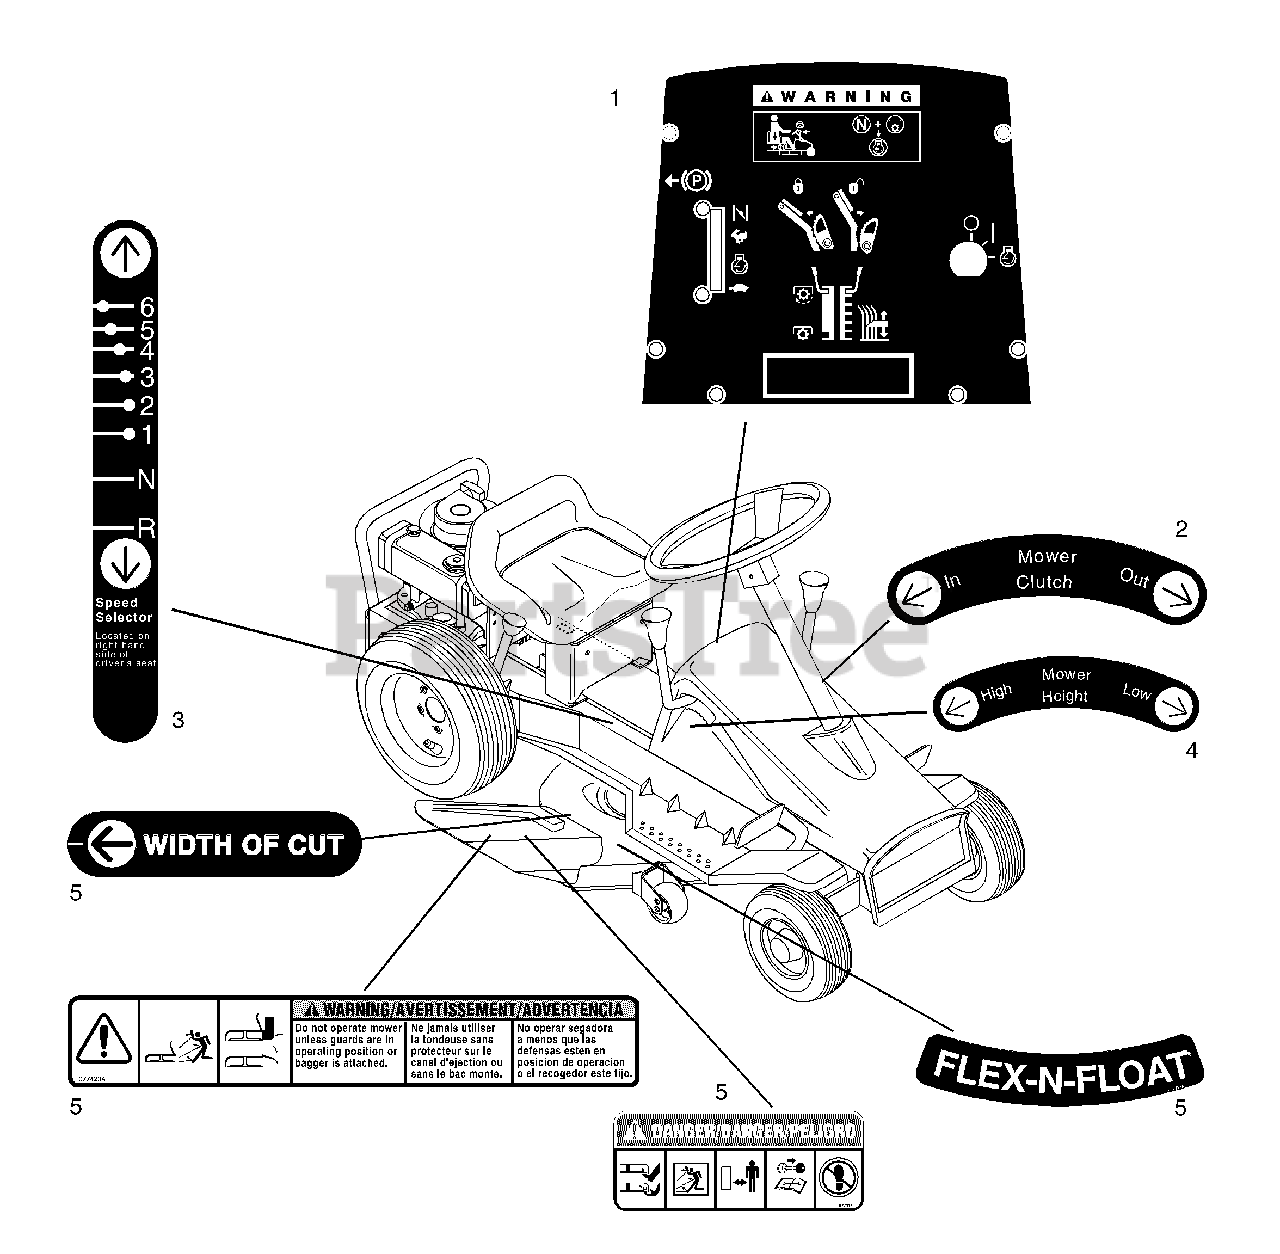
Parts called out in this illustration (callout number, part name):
1	DECAL SET - RM DASH
2	MOWER CLUTCH DECAL
3	DECAL - SPEED SELECTOR
4	MOWER HEIGHT DECAL
5	DECAL SET - DECK
